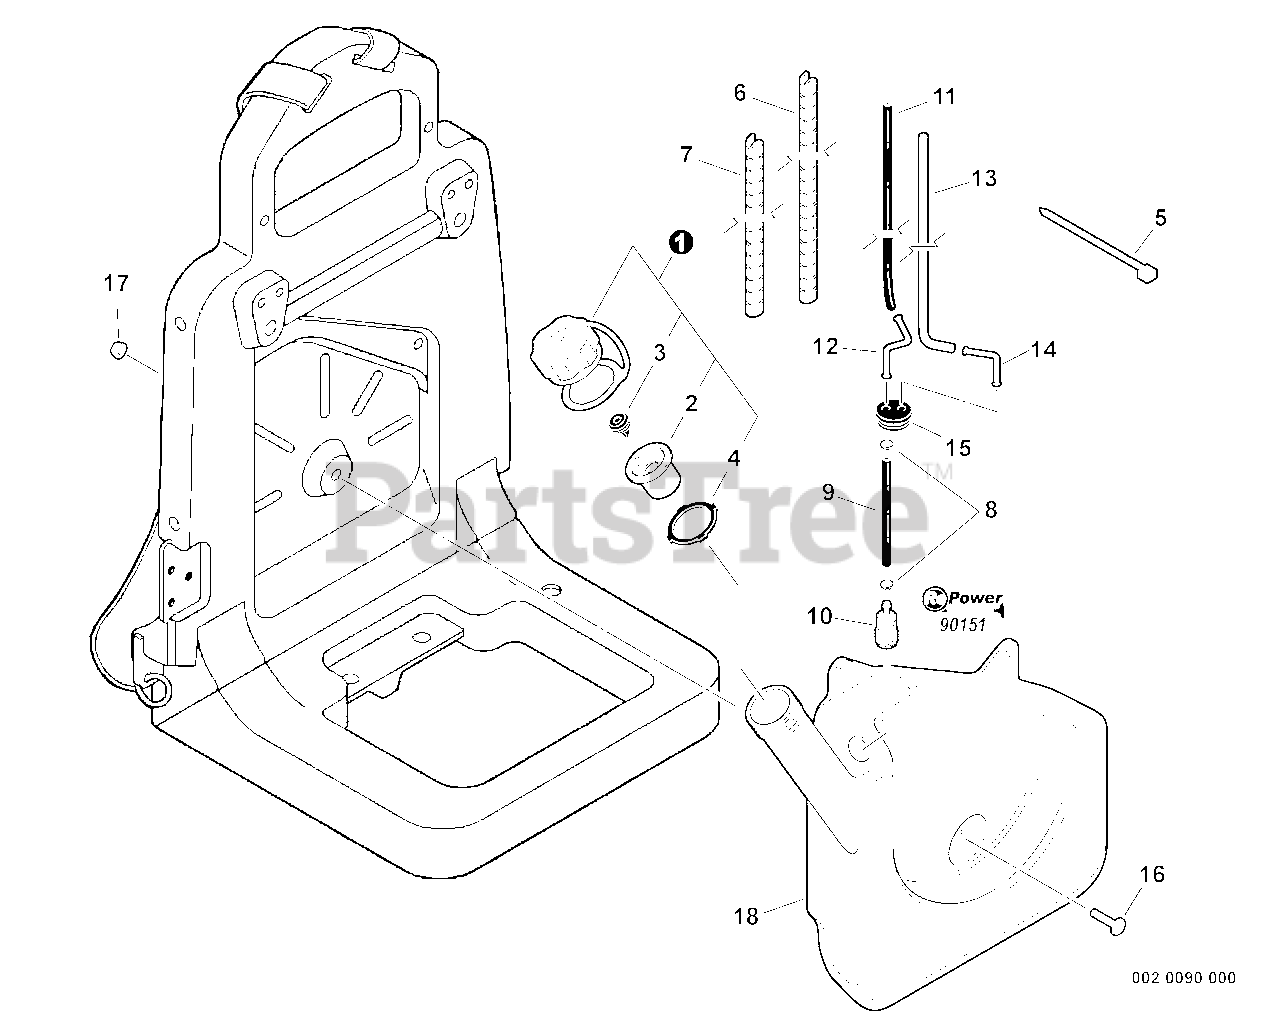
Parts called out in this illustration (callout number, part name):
1	CAP ASSY, FUEL
2	HOLDER, VENT
3	VENT ASSY
4	GASKET, FUEL CAP
5	STRAP, TIE
7	WRAP, SPIRAL
8	CLIP Ø6.5 MM
9	PIPE, FUEL 3×6×280 MM
10	FILTER, FUEL
11	PIPE, FUEL
12	CONNECTOR, PIPE
13	PIPE, FUEL
14	CONNECTOR, PIPE
15	GROMMET
16	SCREW 5×20
17	NUT, FLANGE M5
18	TANK, FUEL
19	TUNE-UP KIT - REPOWER
